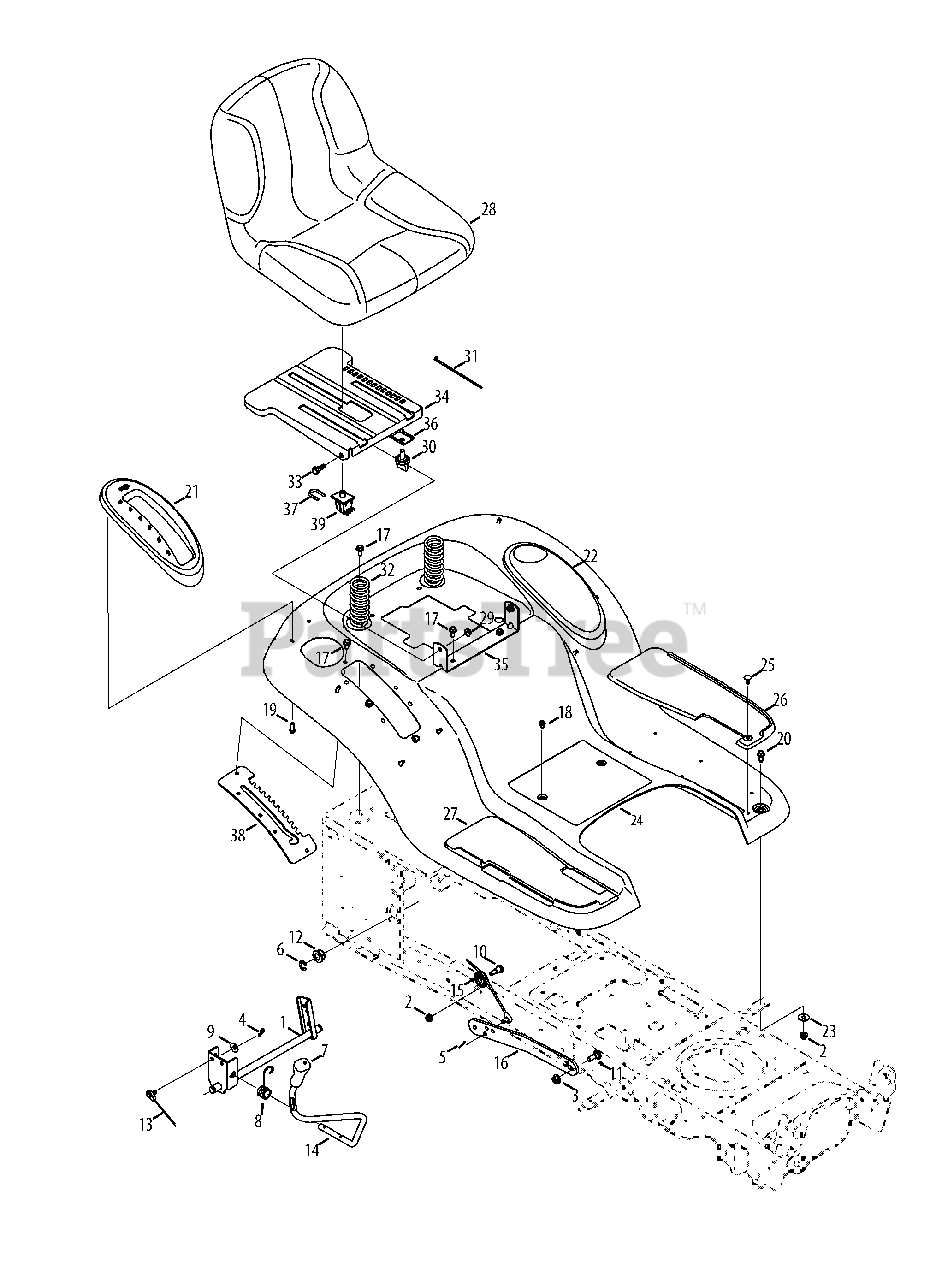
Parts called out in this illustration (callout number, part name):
1	Lift Shaft Assembly
2	Flangelock Nut, 5/16-18
3	Flangelock Nut, 3/8-16
4	Cotter Pin, .072 DIA. x 1.13 LG
5	Bow-Tie Cotter Pin
6	E-Ring, .625 DIA. SHAFT
7	Handle Grip
8	Torsion Spring
9	Spring Washer, .401 x .870 x .063
10	Shoulder Screw, .437 x .470:5/16-18
11	Shoulder Bolt, .500 x .270:3/8-16
12	Hex Flange Bearing
13	Lift Cable, 16.64 LG
14	Lift Handle
15	Pulley Roller Cable
17	Taptite Screw, Lock Washer, 5/16-18
18	Taptite Screw, Lock Washer, 1/4-20
19	Hi-Lo Screw, Lock Washer, 1/4-15
20	Taptite Screw, 5/16-18:.750
21	Lift Lever Cover
22	Cover with Cup Holder
23	Flat Washer, .344 x 1.00 x .063 HDN
25	Ratchet Clip
26	LH Foot Pad
27	RH Foot Pad
28	Seat
29	Flangelock Nut, 5/16-18
31	Cable Tie, 3/16 x .05 x 7.4
32	Compression Spring, 1.50 x 3.90 x .200
33	Shoulder Screw, .437 x .268:5/16-18
34	Seat Mounting Bracket
35	Seat Pivot Bracket
36	Knob Adjust Bracket
37	Switch Retainer Clip
38	Lift Bracket
39	Seat Switch
